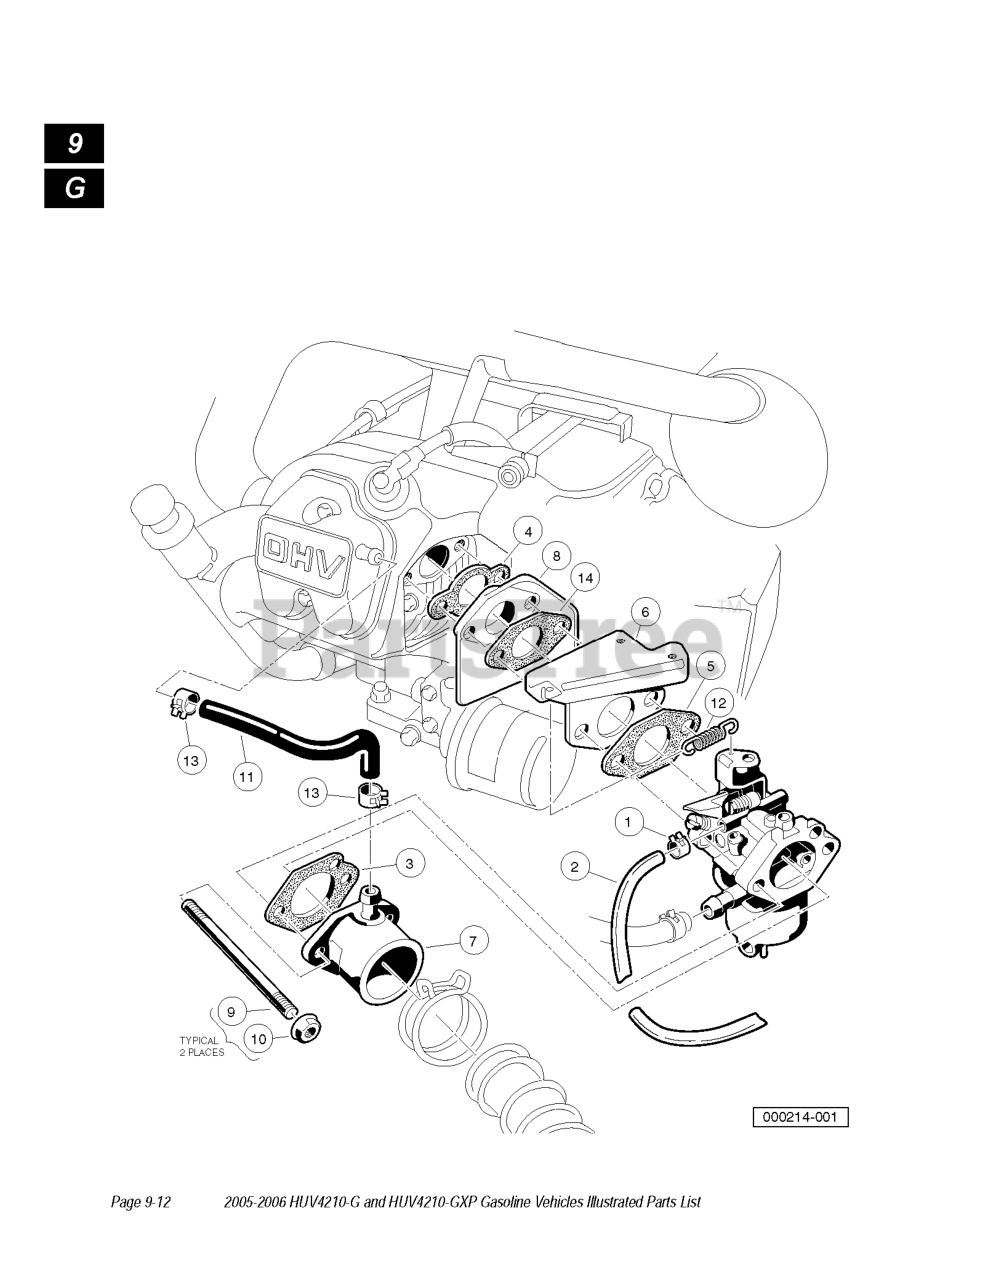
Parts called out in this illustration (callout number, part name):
2	FUEL LINE
3	GASKET, CARB TO INTAKE MANIFOL
4	GASKET, ENGINE TO INSULATOR
5	GASKET, SPRG BRKT TO CARB OHV
6	BRACKET, THROTTLE SPRG RETURN
7	PIPE, INTAKE MANIFOLD
8	INSULATOR, CARBURETOR
9	STUD, M6-1.00 2-ENDED
11	TUBE, CRANKCASE VENT
12	SPRING, THROTTLE RETURN
14	GASKET, INSULATOR TO BRACKET
